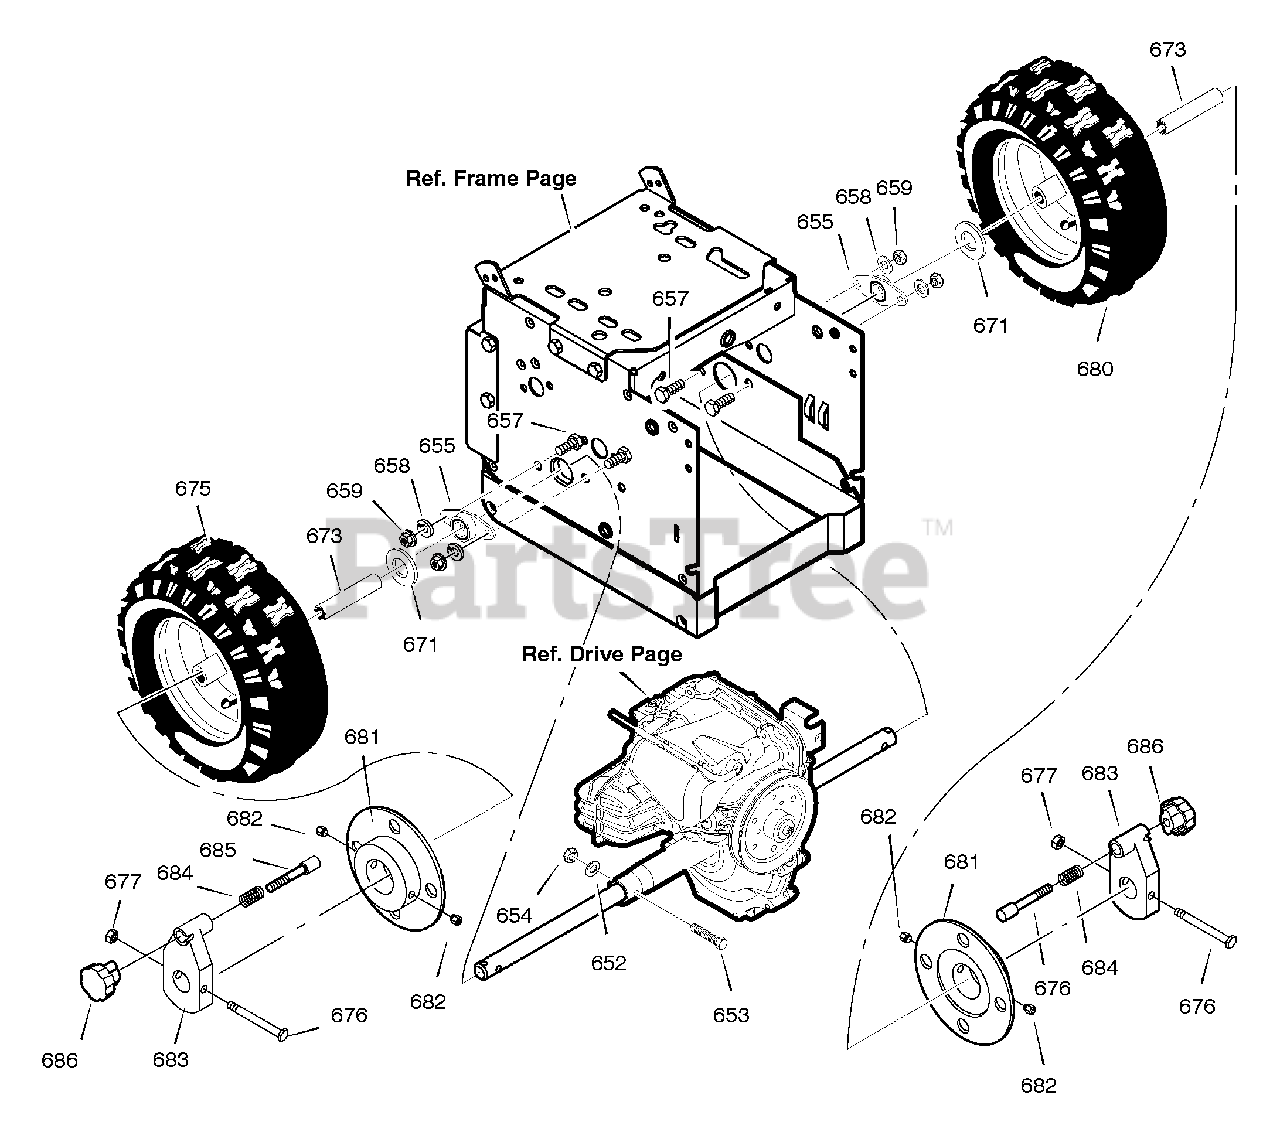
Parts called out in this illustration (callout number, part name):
652	SPACER, SLEEVE
653	SCREW, 1/4-20X1.75
654	NUT, 1/4-20
655	BEARING & RETAINER ASSY
657	SCREW, 3/8-16 x .75
658	WASHER, SPLTLK
659	NUT, 3/8-163
671	WASHER, FLAT
673	BUSHING, WHEEL
675	TIRE & RIM, RIGHT
676	SCREW, 1/4-20 X 2.25
677	NUT, 1/4-20
680	TIRE & RIM, LEFT
681	DISC, WHEEL
683	HUB, WHEEL LOCK
684	SPRING
685	PIN, LOCK
686	KNOB
